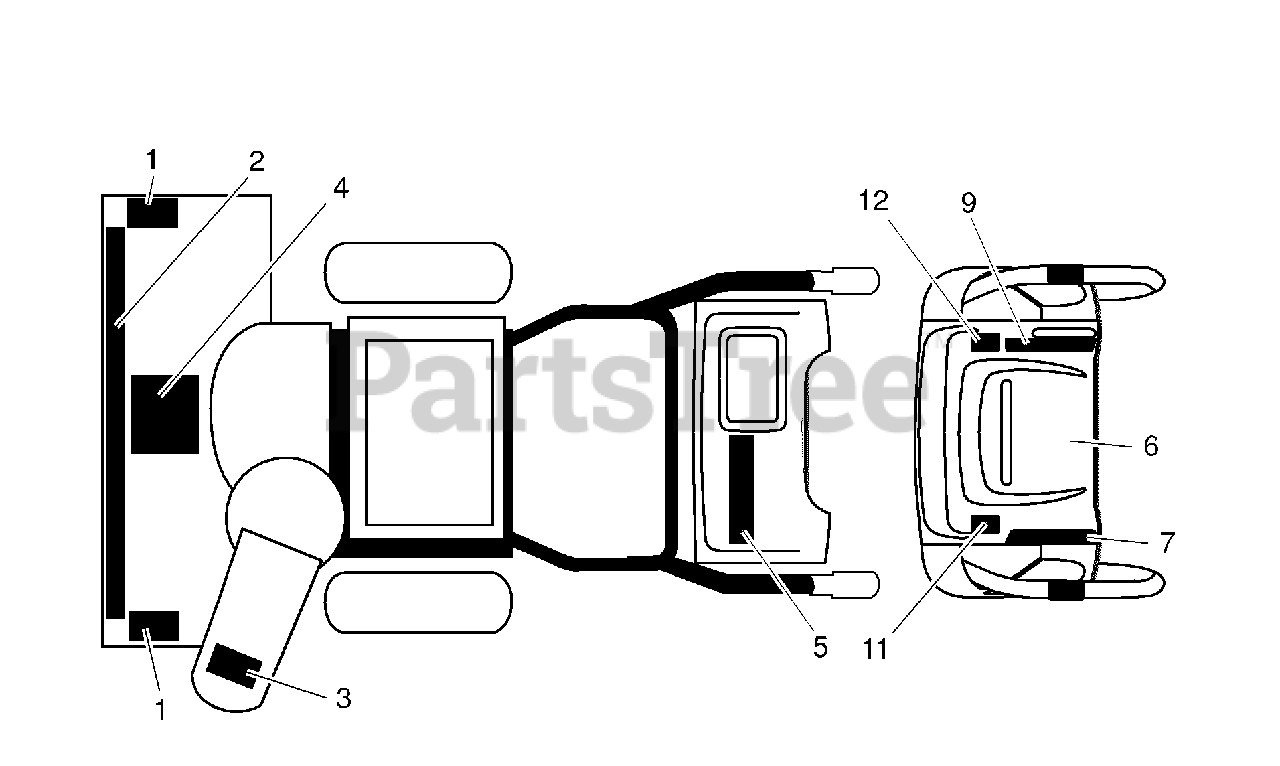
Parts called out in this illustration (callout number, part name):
1	DECAL, DANGER
2	DECAL, HUSQVARNA 1330SB-XLS
3	DECAL, DANGER, DEFLECTOR
4	DECAL, DANGER
5	DECAL, HUSQVARNA
6	DECAL, INSTRUCTION
7	DECAL, REMOTE DEFLECTOR
9	DECAL, SPEED CONTROL
11	DECAL, LH TRIGGER
12	DECAL, RH TRIGGER
12	OWNER'S MANUAL, ENGLISH
12	OWNER'S MANUAL, FRENCH
